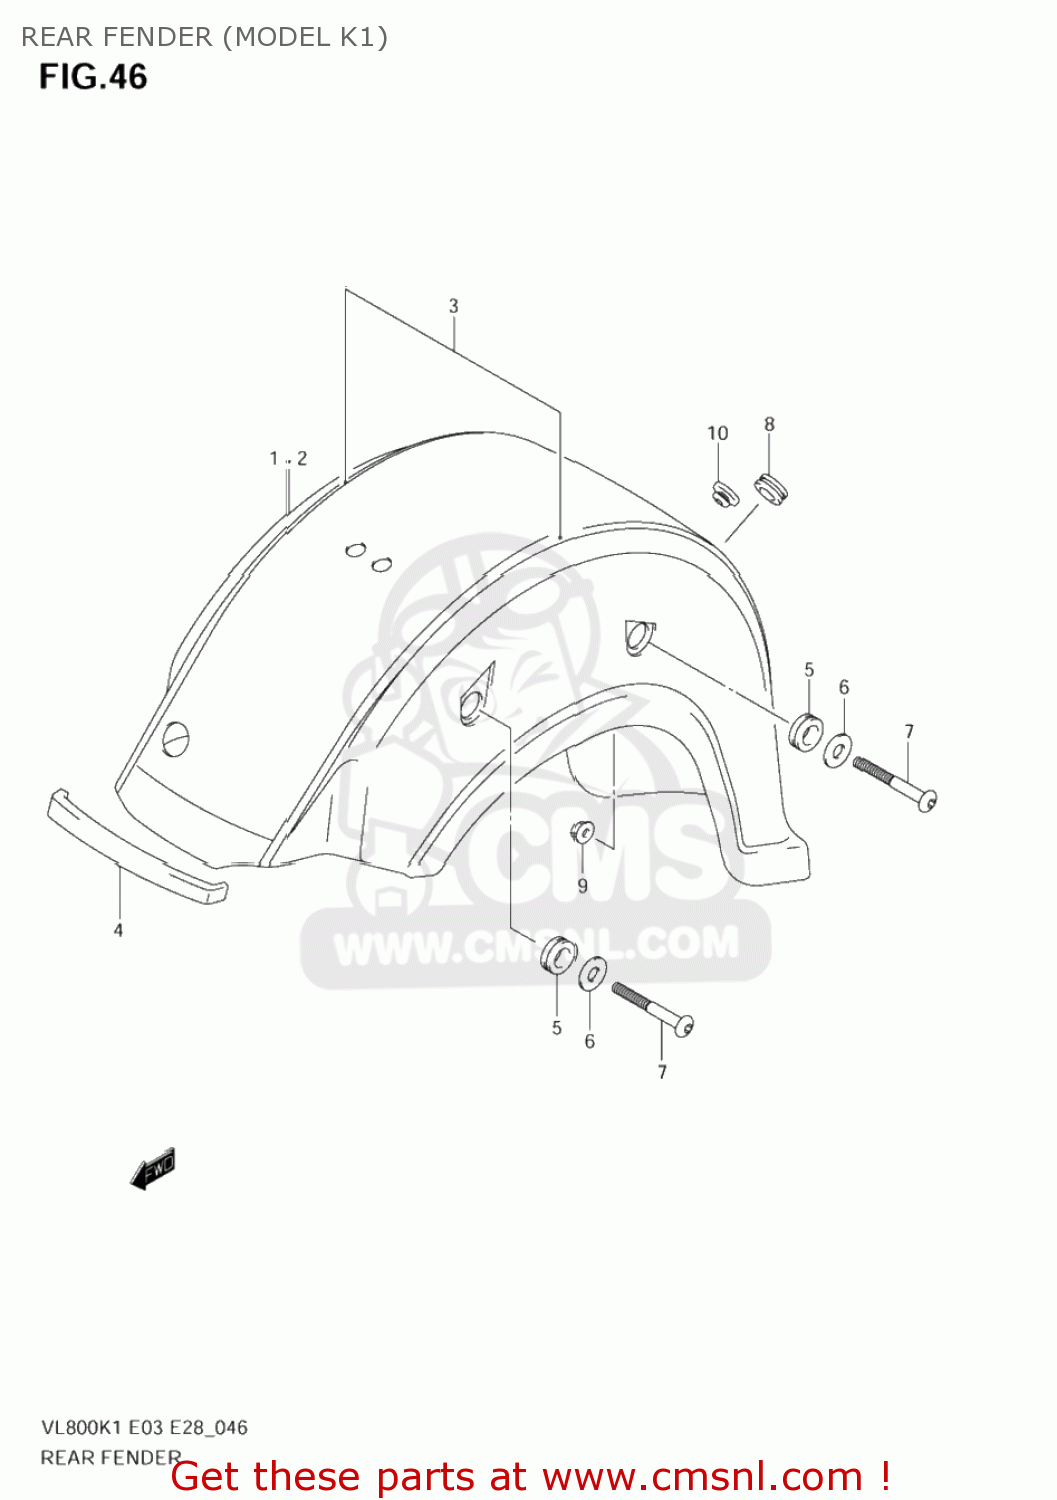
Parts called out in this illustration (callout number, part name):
1	FENDER,REAR
2	FENDER,RR
3	TAPE SET,RR FENDER
4	SEALER,SIDE COVER L
5	CUSHION,FRAME COVER UPR RR
6	WASHER(15.5X26X2.3)
7	BOLT,RR FENDER
8	CUSHION
9	NUT
10	CUSHION
